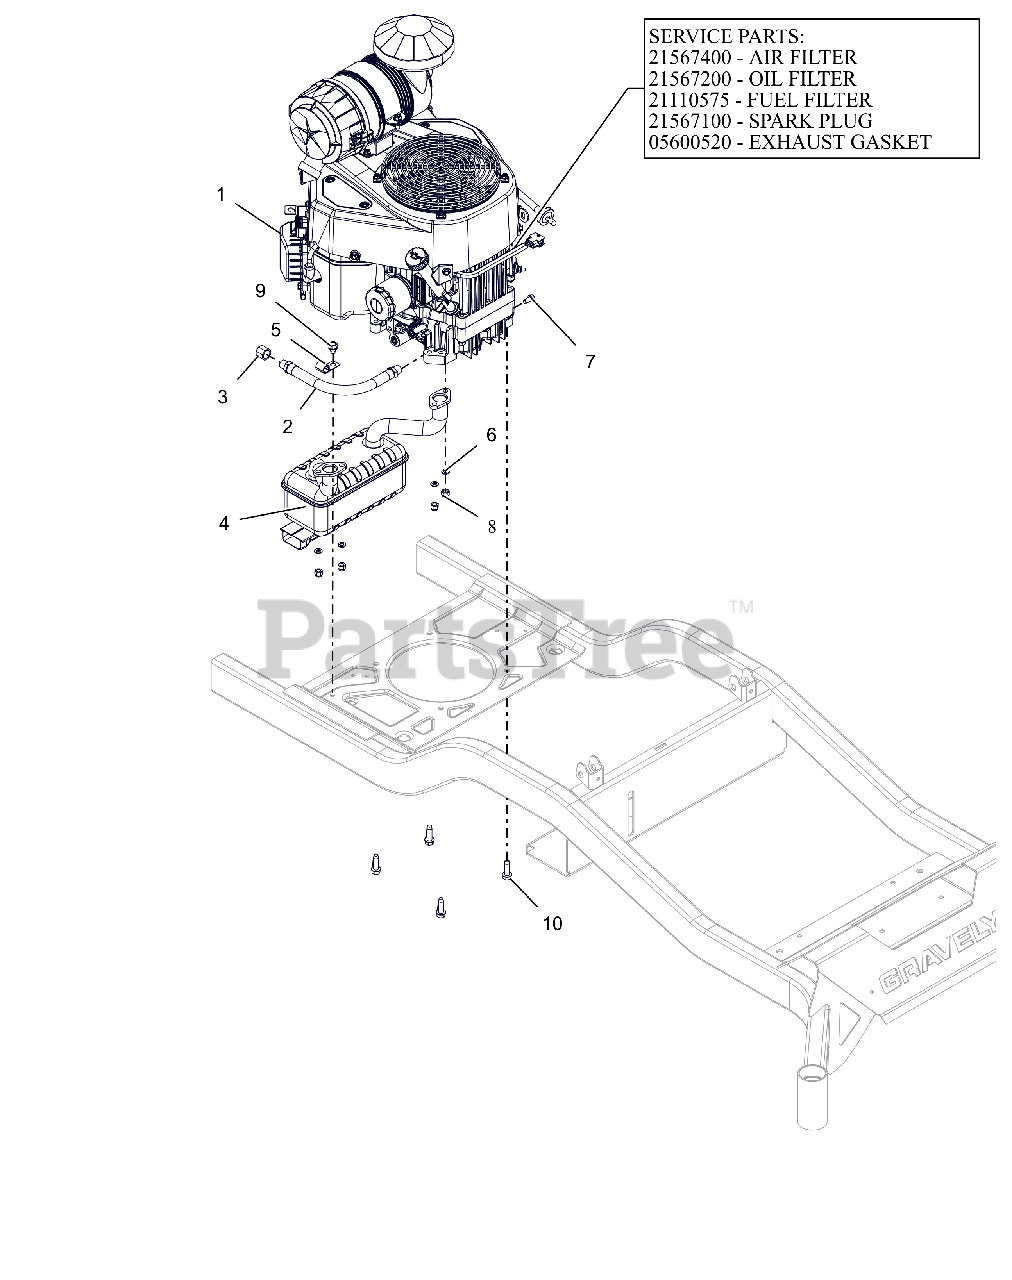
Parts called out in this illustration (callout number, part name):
1	ENGINE, LONCIN 764cc
1	FILTER, AIR
1	FILTER, OIL LONCIN
1	FILTER, FUEL
1	PLUG, SPARK
1	GASKET, MUFFLER LONCIN
2	HOSE,HYD .38-11-0K M6NO-M6N0
3	PIPE CAP 3/8 NPT FEMALE
4	MUFFLER,
6	WSHR,LK-REG .312X.078 ZCC
7	BLT, HEX .31-18X.625 G5 ZCC
8	NUT,NYL M8-1.25 G8.8 ZCC
9	SCR,TAP .375-16X.50 HWH TR ZCC
10	SCR,TAP .375-16X1.25HWH TR ZCC
